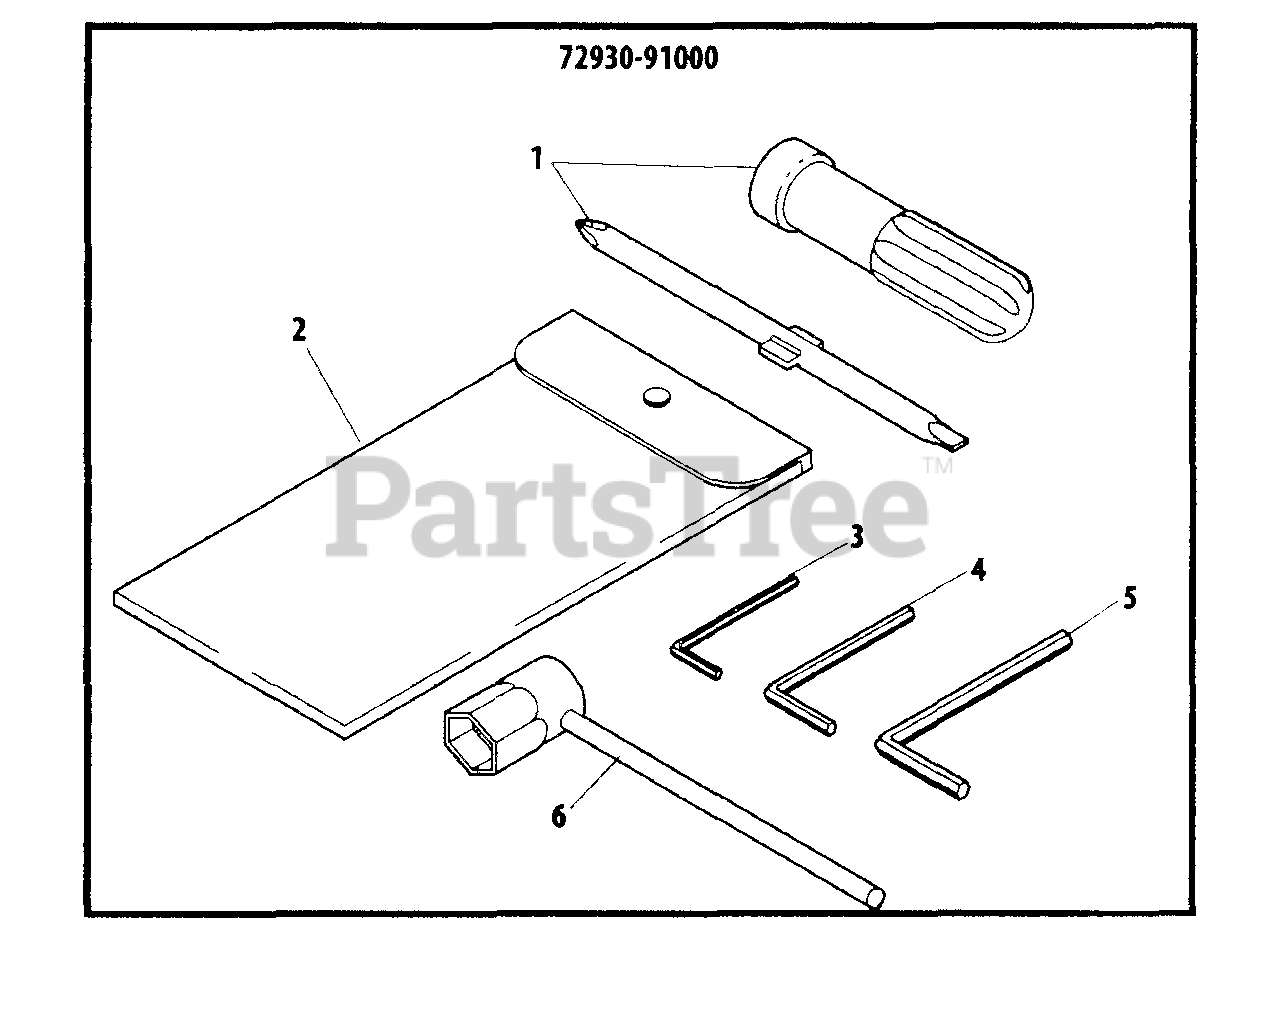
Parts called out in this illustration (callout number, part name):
1	SCREWDRIVER
2	BAG, TOOL
3	HEX KEY - 3mm
4	HEX KEY - 4mm
5	HEX KEY - 6mm
6	SOCKET WRENCH
72930-91000	TOOL KIT
